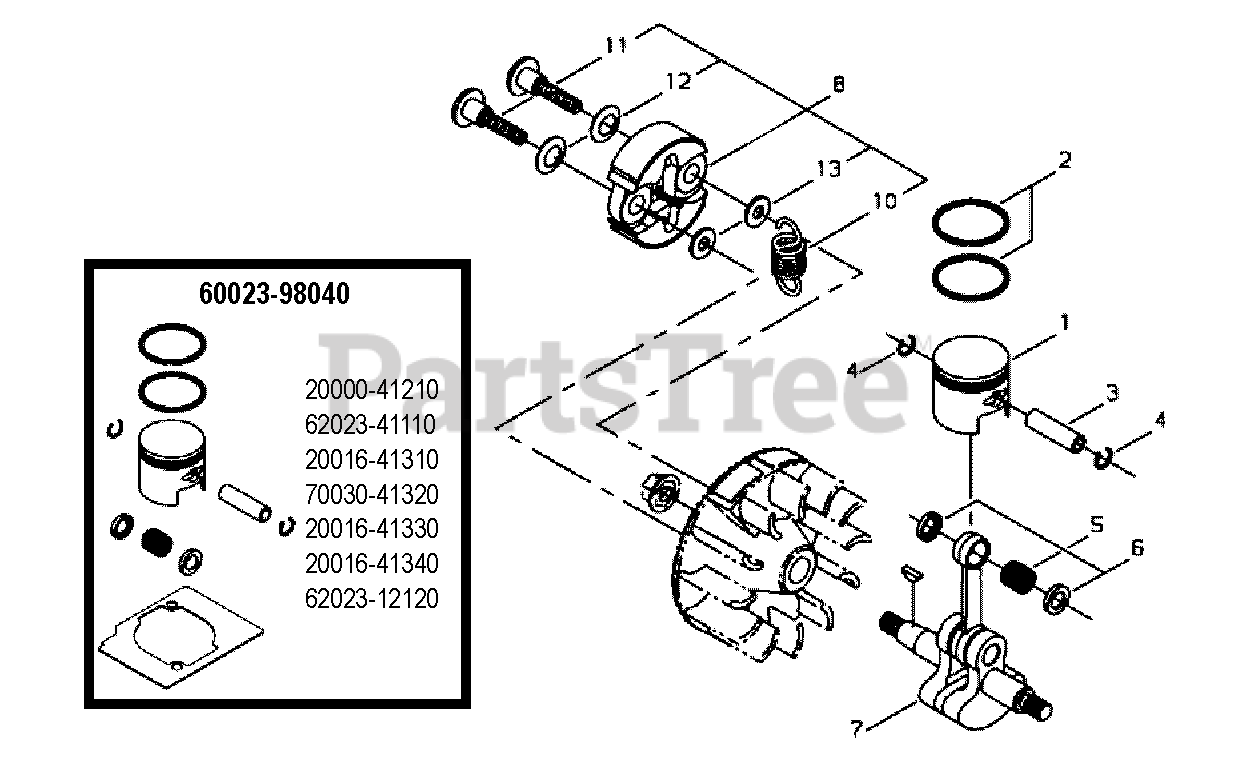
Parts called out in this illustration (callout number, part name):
1	PISTON
2	RING, PISTON
3	PIN, PISTON
4	RING, SNAP
5	BEARING, NEEDLE
6	WASHER, THRUST
7	CRANKSHAFT
8	CLUTCH ASSY
10	SPRING, CLUTCH
11	BOLT, CLUTCH
12	WASHER, SPRING
13	WASHER 6 MM
